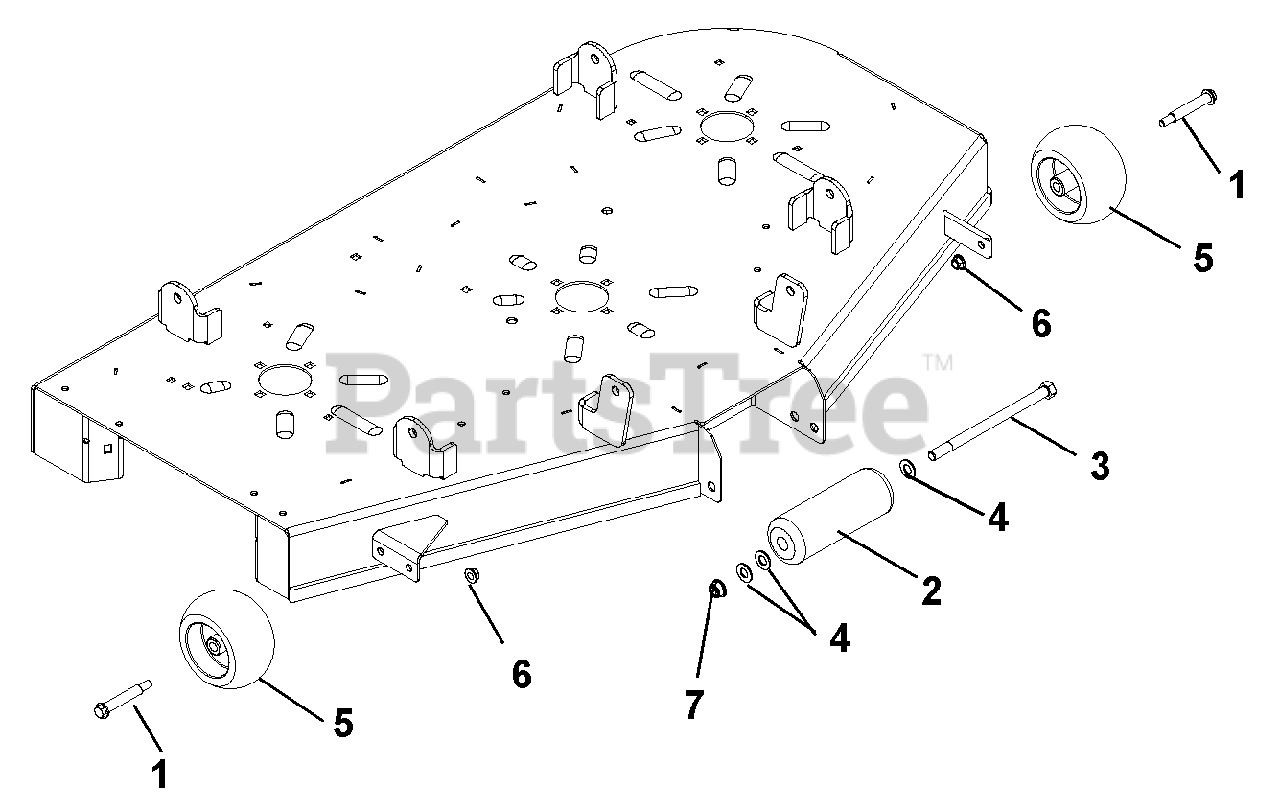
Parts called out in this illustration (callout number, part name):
1	BLT-SHLDR .38-16X2.50 HWH G5
3	@BLT-HEX .50-13X8.00 GR5 YWZC
4	WSHR-FL-NYL .518X1.000X.080
5	ANTI-SCALP WHEEL - 5X OS
6	@NUT-LK-TOP-FLG .38-16 YWZC
7	@NUT-LK-NYL .50-13 YWZC
